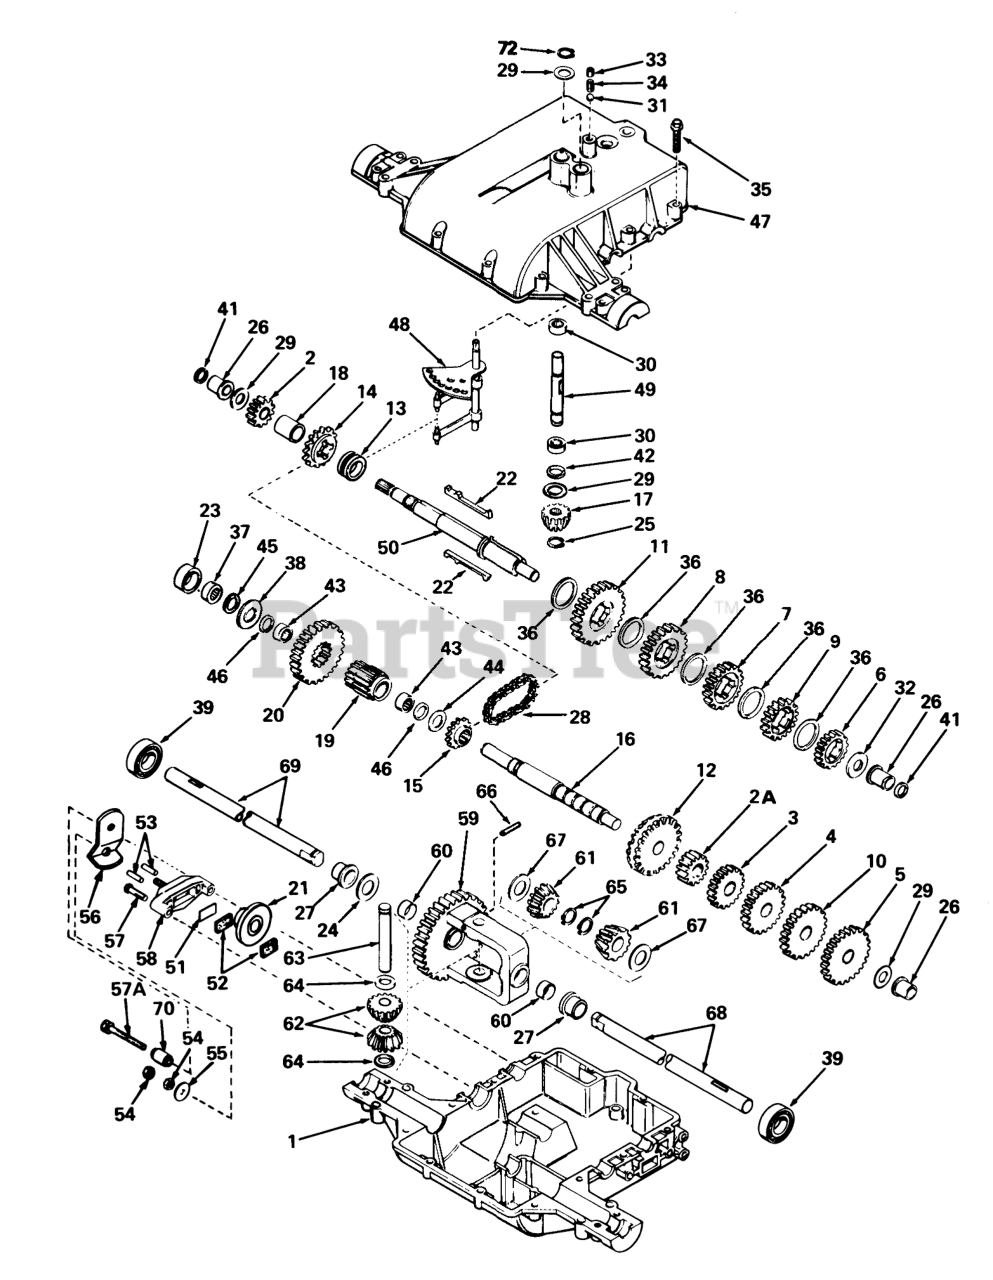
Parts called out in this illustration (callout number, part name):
1	Case-Transaxle
2	Gear-Spur 15 Teeth
2A	Gear-Spur, 12 Teeth
3	Gear-Spur, 20 Teeth
4	Gear-Spur, 25 Teeth
5	Gear-Spur (30 teeth)
6	A Gear-Spur (20 teeth)
7	Gear-Spur, 25 Teeth
8	Gear-Spur, 30 Teeth
9	Gear-Spur (22 teeth)
10	Gear-Spur (28 teeth)
11	Gear, Spur (37 teeth)
12	Gear, Bevel (42 teeth)
13	Collar-Shift
14	Sprocket-18 Teeth
15	Sprocket-9 Teeth
16	Shaft-Counter
17	Bevel Pinion-Input
18	Spacer
19	Pinion-Output
20	Gear-Output
23	Spacer
24	Washer
25	Ring-Retainer
26	Bushing, Flanged
27	Bushing, Flanged
28	Chain-Roller #41
29	Washer
30	Bearing-Needle
31	Ball-Steel
32	Washer
33	Screw-Set
34	Spring
35	Ring Set (.020 O S)
36	Washer
37	Bearing-Needle
38	Washer-Flat
39	Bearing-Ball
41	Ring-Square Cut
42	O Ring
43	Bearing-Needle
44	Washer-Flat
45	Ring-Square Cut
46	Ring-Square Cut
47	Cover-Transaxle
48	Rod & Fork Assembly
49	Shaft-Input
50	Shaft, Brake
51	Brake Pad Plate
52	Brake Pad
53	Dowel Pin
54	Locknut
55	Washer
56	Lever-Brake
57	Ring Set (.020 O S)
57A	Screw-Hex. Flange
58	Holder-Brake Pad
59	Gear Assy., Differential (Incl. 2 of No. 60)
60	Bushing
61	Bevel Gear
62	Gear Pinion
63	Drive Pin
64	Thrust Washer
65	Ring-Snap
66	Pin-Roll
67	Washer
68	Axle (14 7/8" long)
69	Axle (13" long)
70	Spacer
72	Ring-Snap
